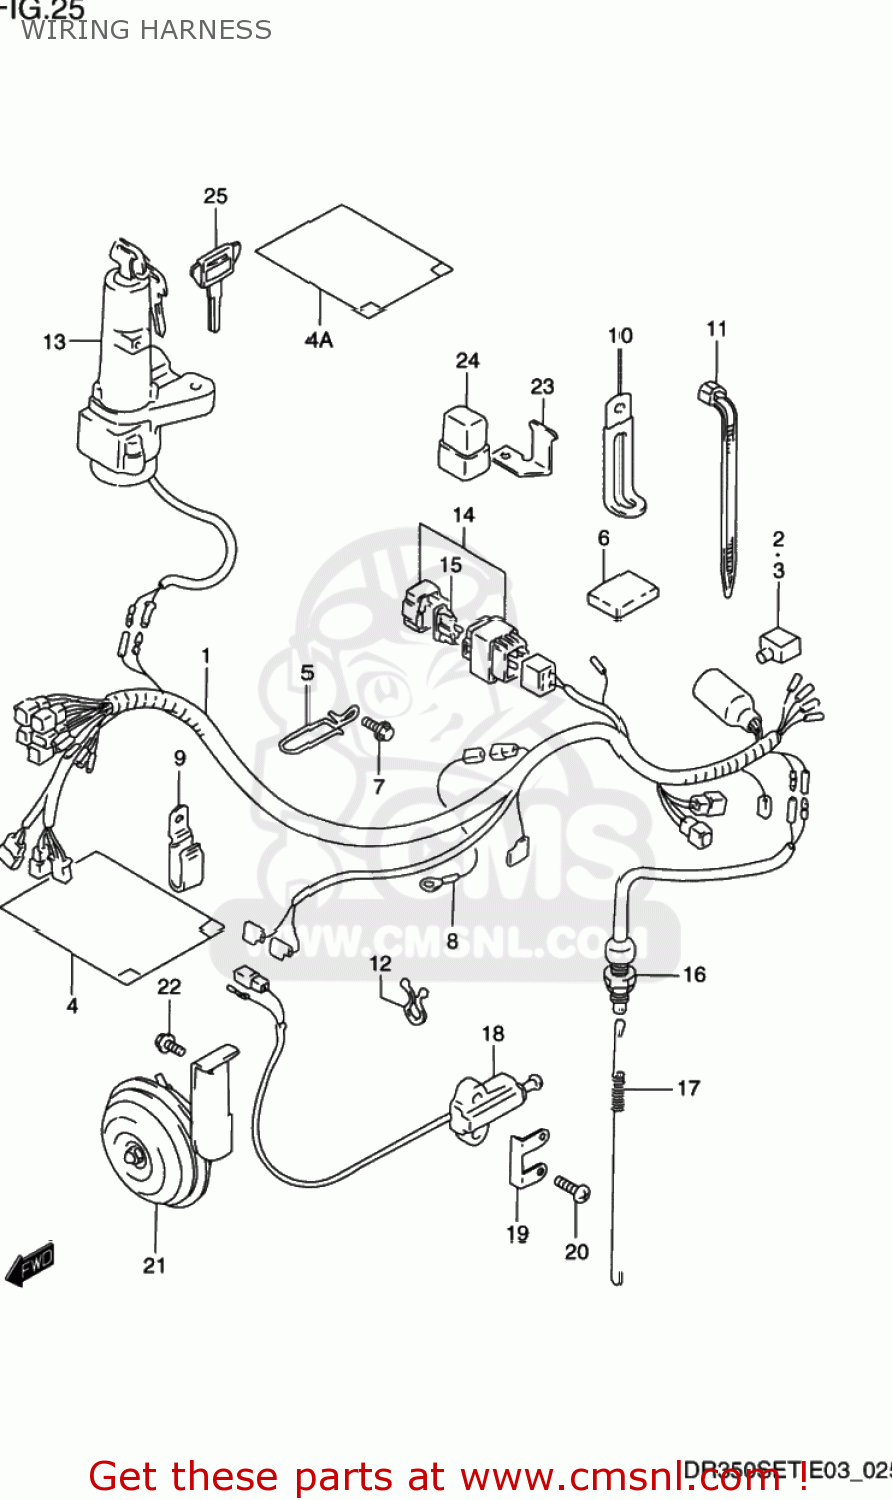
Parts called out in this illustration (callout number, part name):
1	HARNESS,WIRING
2	CAP,BATTERY PLUS
3	CAP,BATTERY PLUS TERMINAL
4	COVER,WIRING HARNESS
4A	COVER,WIRING HARNESS
5	GUIDE,WIRING HARNESS
6	PROTECTOR,WIRING HARNESS
7	BOLT
8	WIRE
9	CLAMP
10	CLAMP
11	CLAMP
12	CLIP(ID:11.5)
13	SWITCH ASSY,IGNITION
14	BOX ASSY,FUSE
15	FUSE(15A)
16	SWITCH ASSY,STOP LAMP
17	SPRING
18	SWITCH ASSEMBLY,SIDE STAND
19	PROTECTOR,SIDE STAND SWITCH
20	SCREW
21	HORN ASSEMBLY
22	BOLT
23	BRACKET,FUSE
24	RELAY ASSY
25	KEY,BLANK(TYPE:C)
